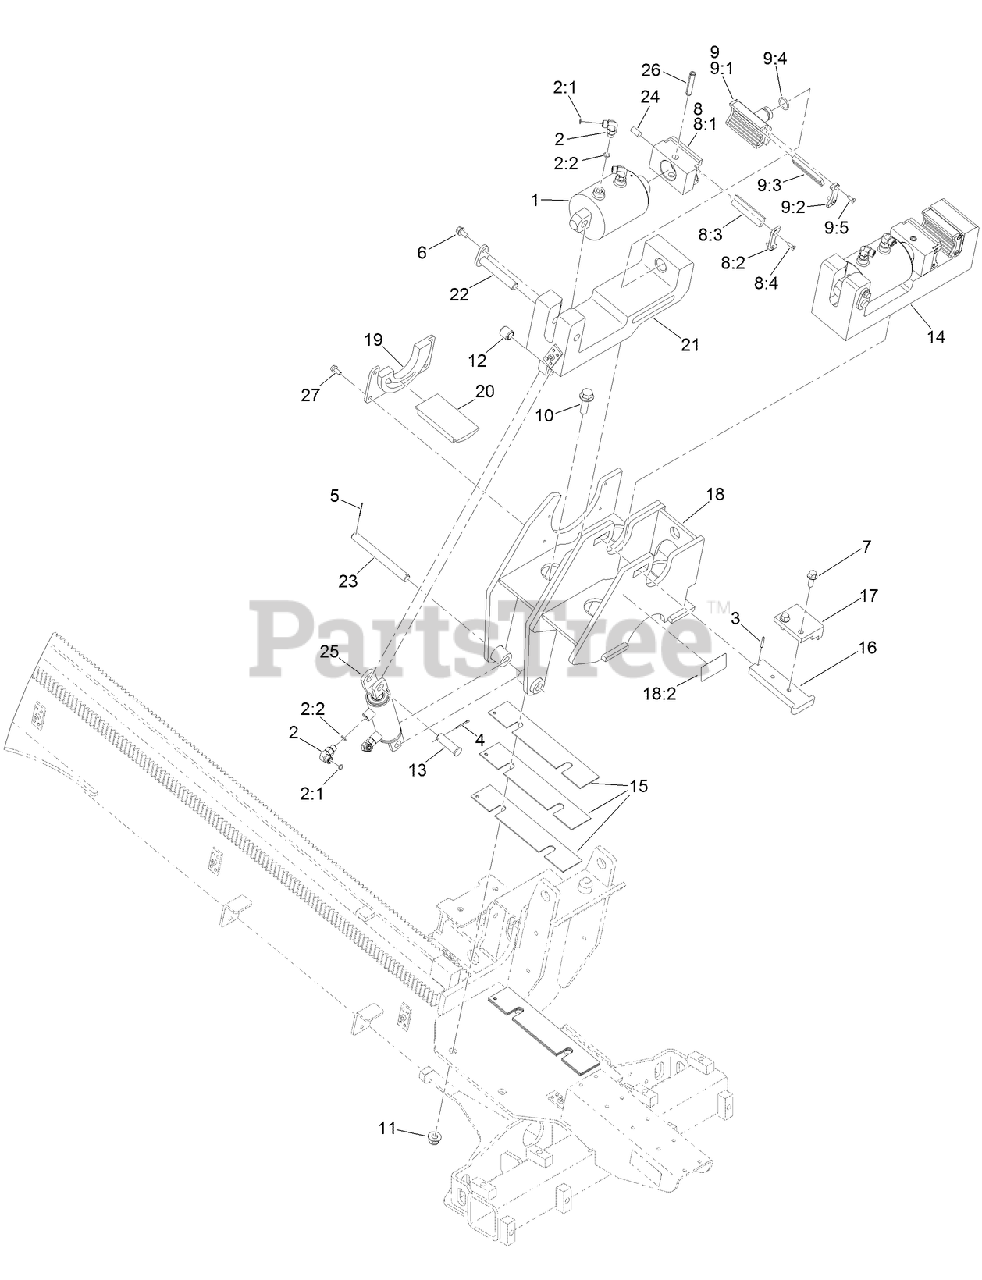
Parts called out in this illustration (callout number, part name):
1	HYD CYLINDER ASM
2	FITTING-ELBOW, 90 DEG
2:1	O-RING
2:2	O-RING
3	SCREW-HH
4	PIN-COTTER
5	PIN-COTTER
7	SCREW-HHF
8	MOVING DIE HOLDER ASM
8:1	HOLDER-DIE, MOVING
8:2	RETAINER-DIE
8:3	TONG-DIE
8:4	SCREW-FH
9	FIXED DIE HOLDER ASM
9:1	HOLDER-DIE, FIXED
9:2	RETAINER-DIE
9:3	TONG-DIE
9:4	SEAL, O-RING
9:5	SCREW-FH
11	NUT-HF
12	BUSHING-SPRING
13	PIN-CLEVIS
14	BASE-FIXED CLAMP
15	PLATE-SHIM
16	PIN-RETAINING
17	BLOCK-STOP, CYLINDER
18	WRENCH ASM
18:2	DECAL-DANGER
19	RETAINER-PIVOT KEY, WRENCH
20	KEY-PIVOT, WRENCH
21	BASE-WRENCH
22	PIN-FLAG
23	PIN-CYLINDER
24	PIN-DOWEL
25	CYLINDER-HYDRAULIC
26	PIN-SPRING
27	SCREW-HHF
